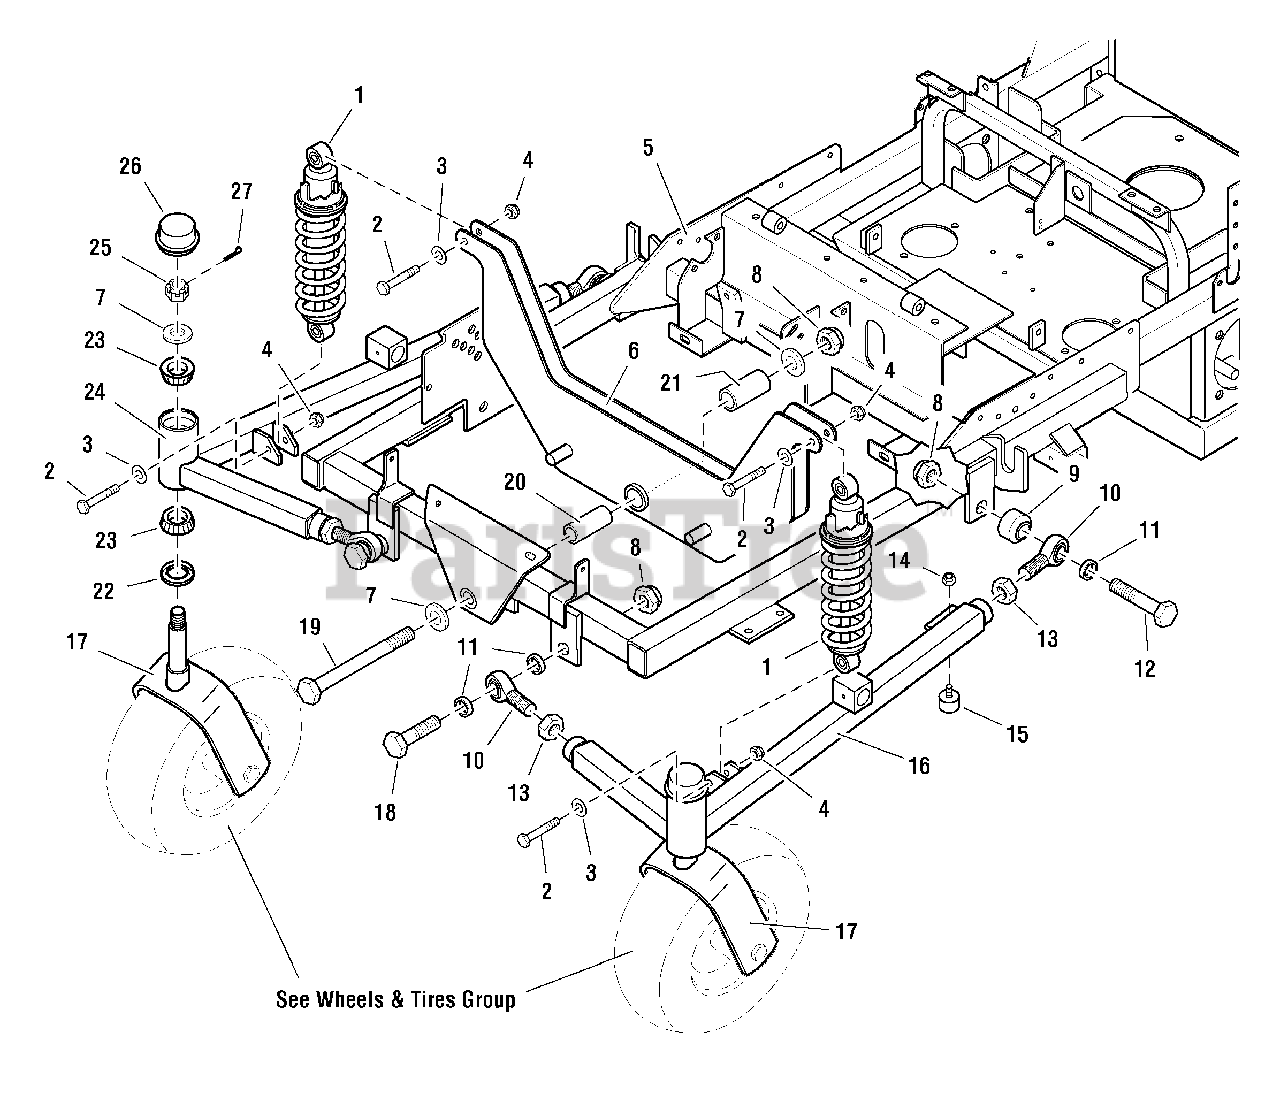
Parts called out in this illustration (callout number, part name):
1	SHOCK & SPRING ASSEMBLY
2	CAPSCREW, Hex Hd, 3/8-16 x 2
3	WASHER, 3/8
4	NUT, Hex, Nylon Lock, 3/8-16
6	UPPER SHOCK MOUNT
7	WASHER, 3/4
8	NUT, Hex, Nylon Lock, 3/4-16
9	SPACER, .75 x 1.50 x 1.00
10	BALL JOINT, 3/4-16
11	SPACER, .76 x 1.00 x .25
12	CAPSCREW, Hex Hd, 3/4-16 x 4
13	NUT, Hex, Jam, 3/4-16
14	NUT, Hex, Nylon Lock, 1/4-20
15	RUBBER BUMPER
16	SUSPENSION ARM-LH
17	CASTER YOKE
18	CAPSCREW, Hex Hd, 3/4-16 x 3
19	CAPSCREW, Hex Hd, 3/4-16 x 6
20	SPACER, .75 x 1.00 x 2.38
21	PIVOT BEARING
22	SEAL, Grease
23	BEARING, Tapered Roller
24	SUSPENSION ARM-RH
25	NUT, Hex, SLotted, 3/4-16
